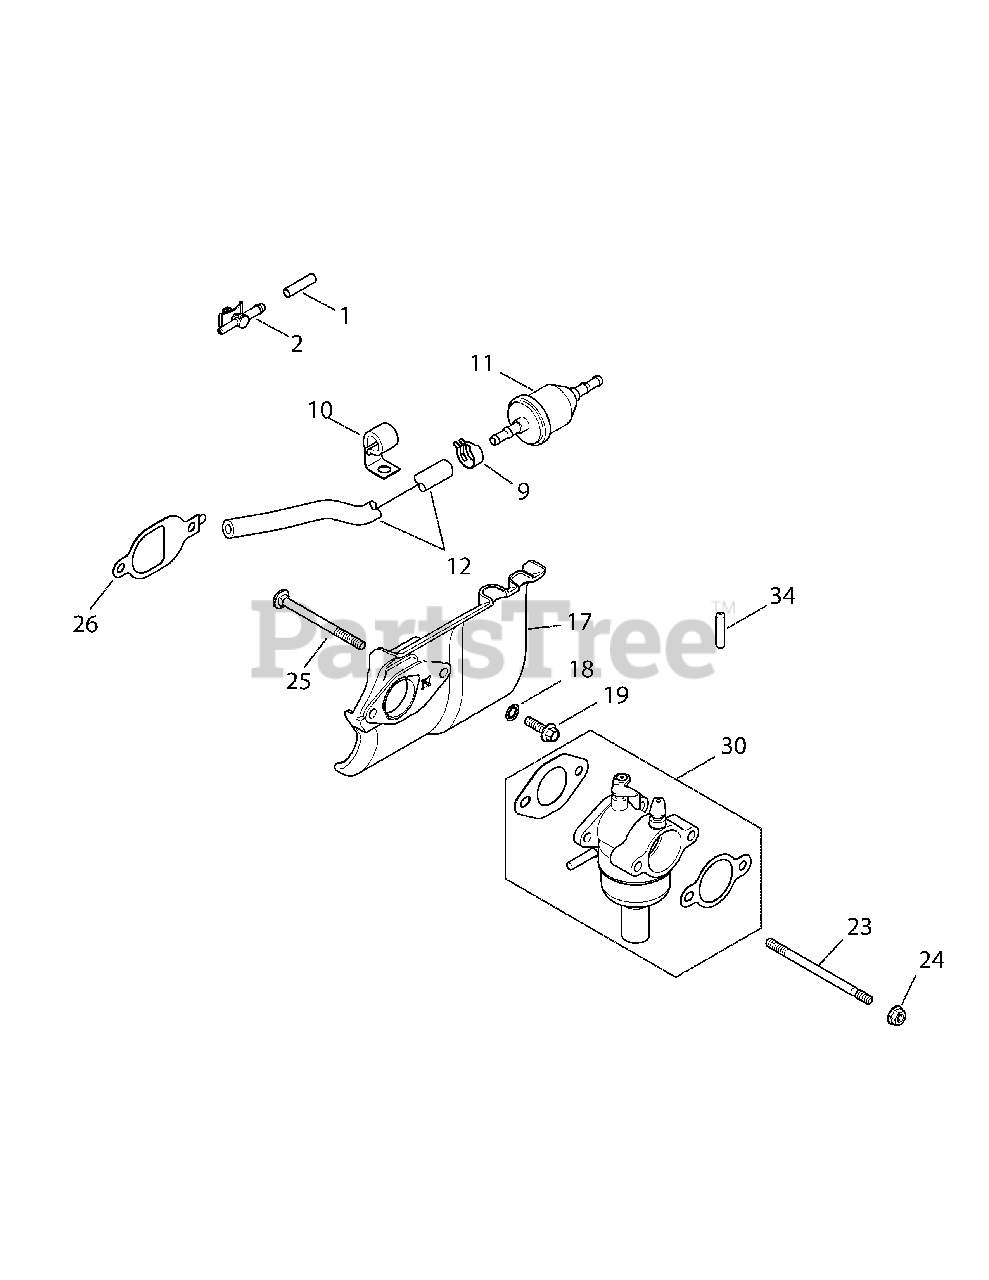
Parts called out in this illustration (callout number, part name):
2	SAI Connector
9	Hose Clamp, 1/2
12	Fuel Line
17	Heat Deflector Kit
18	Int. Tooth Lock Washer, 1/4
19	Flange Screw, M6 X 1.0 X 20
23	Stud, M6 X 1.0 X 100
24	Flange Nut, M6 X 1.0
25	Carburetor Stud
26	Heat Deflector Gasket
30	Carburetor Kit (Inc. 21 & 22)
34	not used in this application
